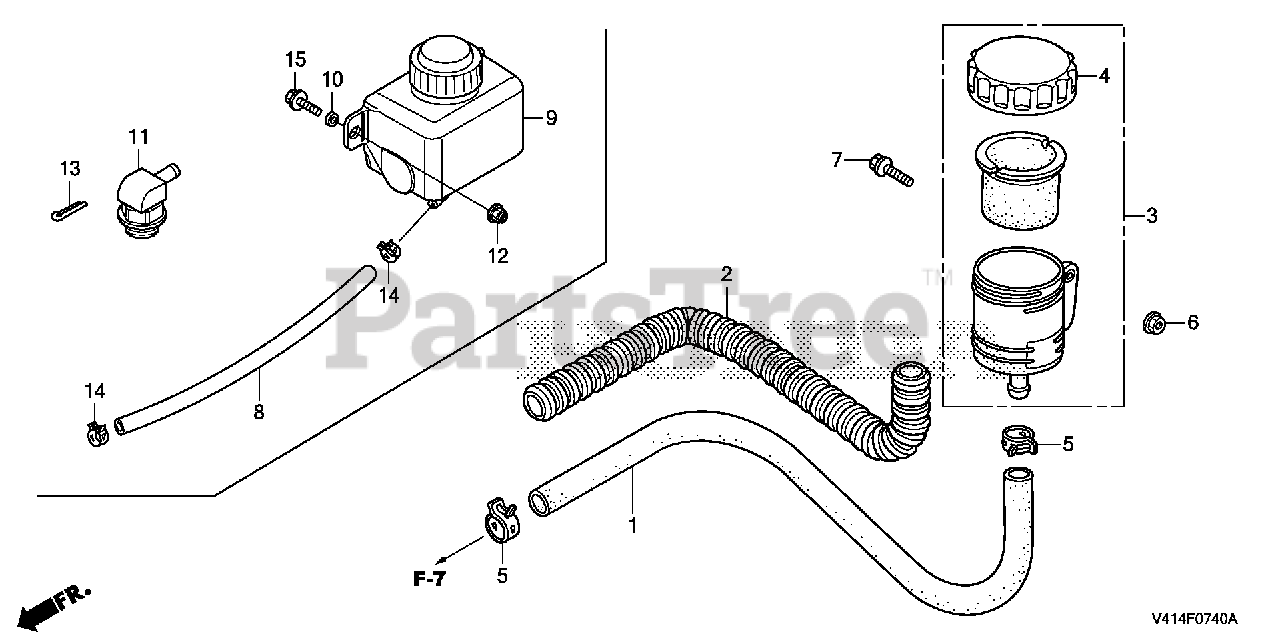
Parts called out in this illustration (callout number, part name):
8	TUBE, OIL
9	TANK, OIL
10	COLLAR, TANK
11	ELBOW ASSY., OIL
12	NUT, NYLON LOCK (6MM)
13	PIN, COTTER (3.0X18)
14	CLIP, TUBE (D8.5)
15	BOLT, FLANGE (6X16)
